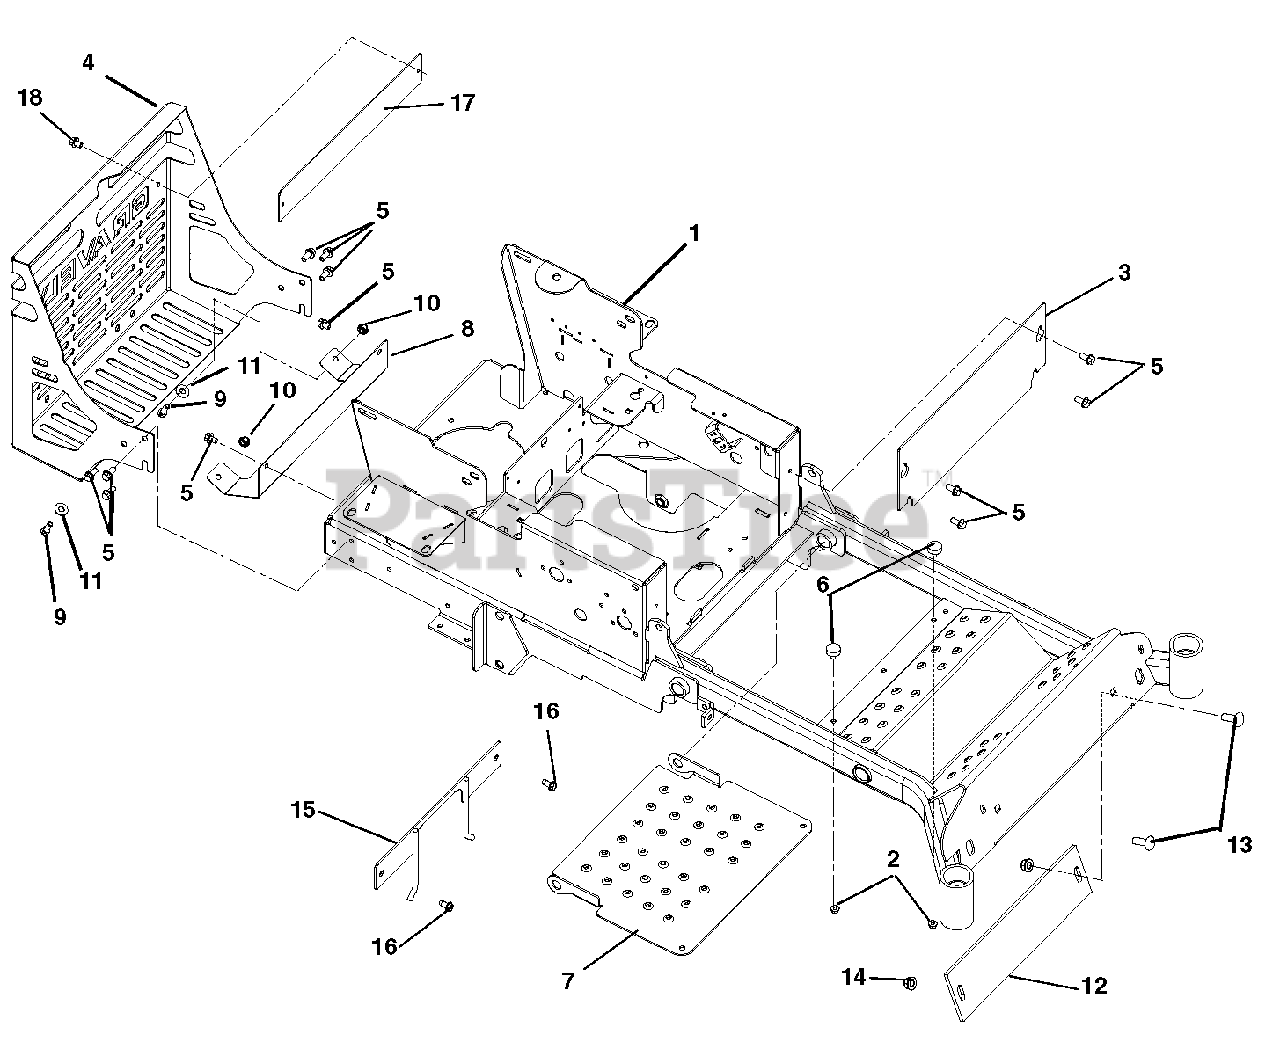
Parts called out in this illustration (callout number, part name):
1	Weldment, CZ 44-48 Main Frame
2	Nut, Spin Lock Flange .312-18
3	Kick Plate
5	Screw, Tapping .38-16 x .75 Hex Washer Head
6	Bumper, Rubber
7	Panel, Inspection
8	Heat Shield
9	Bolt, Hex .38-16 x 1.00 Grade 5
10	Nut, Nyloc Flange .38-16
11	Washer, Flat Steel .438 x 1.00 x .083
12	Counterwieght CZ Front- Red
13	Bolt, Round Head Square Neck .50-13 x 1.75 Grade 5
14	Nut .50-13 Nyloc Flange
15	Weldment, PTO Belt Finger
16	Screw, Tapping .38-16 x .75 Hex Washer Head Thread
17	Bumper Backer Plate
18	Screw, Tapping .25-20 x .50 Hex Washer Head
